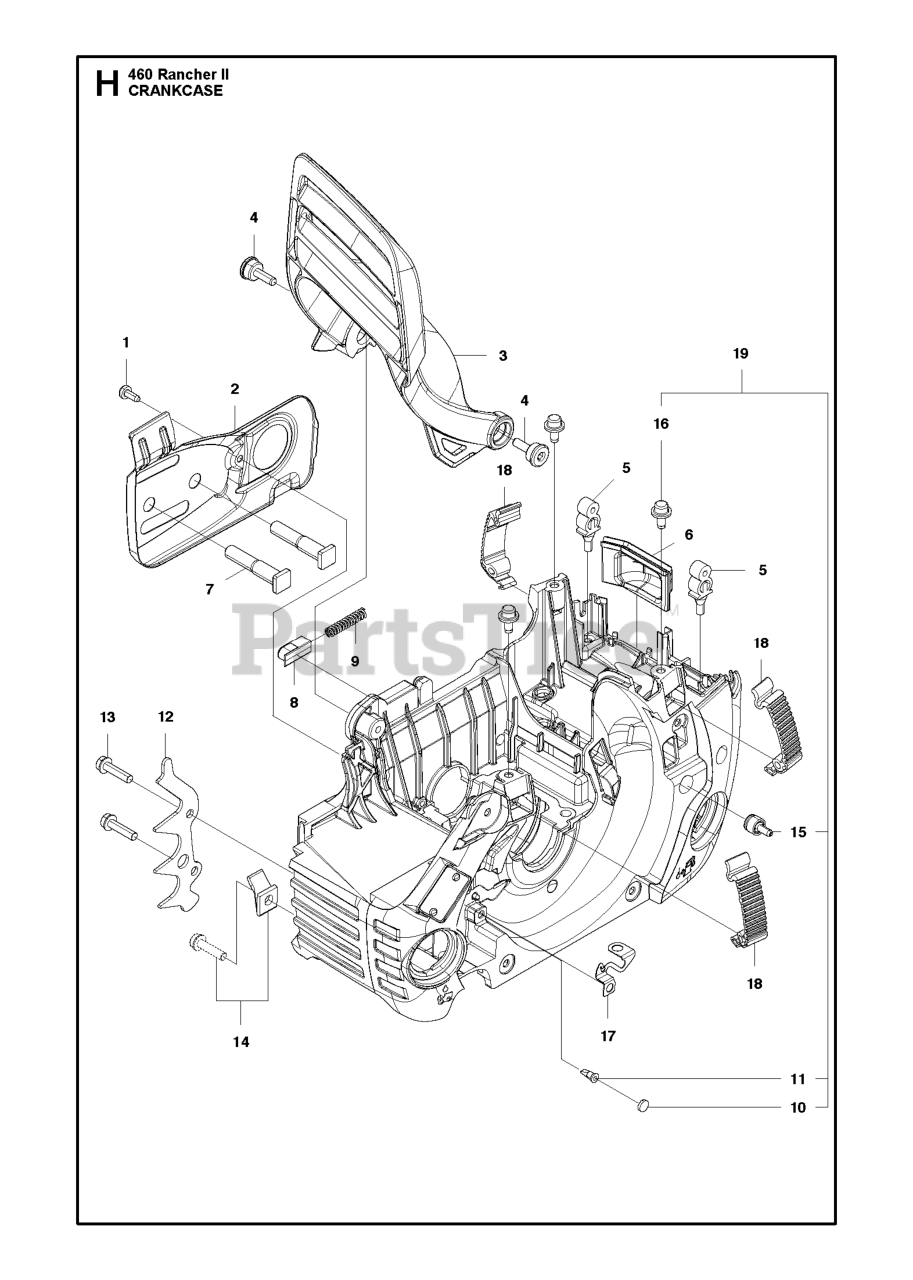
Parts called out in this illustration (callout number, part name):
3	HAND GUARD
4	SCREW, HAND GUARD
9	LOCK SPRING
10	PLUG
11	VALVE-CHECK (DUCKBILL)
13	SCREW IHSCFT
14	CHAIN CATCHER
15	FUEL TANK VENT
17	GROUND PLATE
18	BUCKLE ORANGE
19	CRANKCASE
